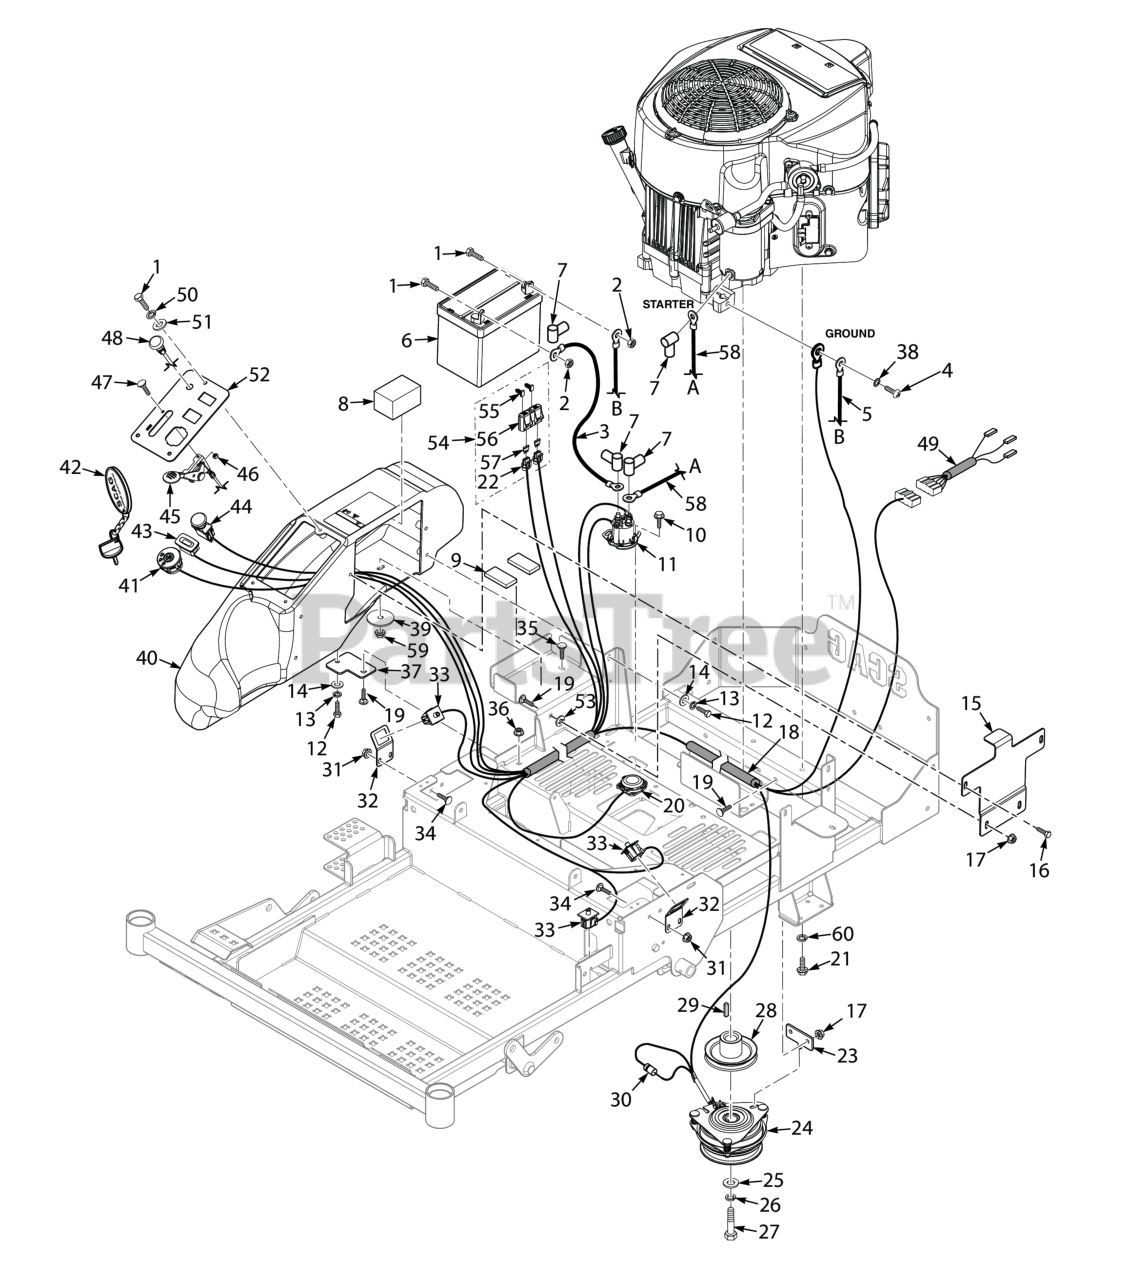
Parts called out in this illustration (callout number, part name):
1	Bolt, Hex Head 1/4-20 x .5" Battery, (Not Available Through Scag)
2	Nut, 1/4 - 20 Hex
3	Battery Cable, 18" Red w/Braid (25KA, 26DFI, 31DFI) - Kawasaki
4	Bolt, Hex Head M8 - 1.25 x 16 (48V / 52V)
5	Battery Cable, 31-1/2" Black (25KA, 26DFI, 31DFI) - Kawasaki
6	Battery, 12v - 230CCA
7	RUBBER BOOT
8	Pad, Battery - Rubber
9	Pad, Battery - Rubber
10	Screw, Self-Tapping 1/4-20 x 3/4
11	Solenoid, Sealed (Briggs & Stratton)
12	BOLT, SERRATED FLANGE HEX HEAD 5/16-18 X 3/4"
13	Lockwasher, 5/16 (.317 x .586 x .078) Helical Spring
14	Flatwasher, 5/16-.375 x .875 x .083 (35BV & 37BV-EFI)
15	Battery Hold Down
16	CAP SCREW, 5/16-18 X 1/2" SERRATED FLANGE HEX
17	Nut, Flange Head Elastic Stop 5/16-18
18	Wire Harness
19	Bolt, 5/16-18 x .75 RHSN Carriage
20	Switch, Double Pole - Twist
21	Bolt, Hex Head 3/8-16 x 1-1/4", Kawasaki FX / FT & FT-EFI
22	Fuse Holder Assembly
23	Plate, Anti-Rotation
24	Clutch, GT2 (SZL-61)
25	Flatwasher, 7/16-.469 x 1.75 x .25 (48, 52)
26	Lockwasher, 7/16� Spring
27	Bolt, Hex Head 7/16-20 x 3¼" w/Patch
28	Pulley, 4-1/2" - 1" Bore
29	Key, 1/4 x 1/4 x 1.25" Pulley Mtg.
30	Diode, 600V 6 Amp
31	Nut, Flanged Elastic Stop 1/4-20
32	Bracket, Switch
33	Switch, Double Pole - Plunger
34	Serr. Fl. Hex Head CPSCR, 1/4-20 x 3/4"
35	Bolt, Carriage 5/16-18x1" (large frame units only)
36	Nut, Serrated Flange 5/16-18 (Right Front Engine Mounting, Briggs and Kohler Only)
37	Mounting Bracket, Fuel Tanks Front
38	Lockwasher, 5/16" Ext. Tooth (Kohler x1)
39	Flatwasher, 3/8-.406 x 2.25" x .1875
40	Console Tank, SZL
41	Ignition Switch
42	Key, Assembly w/Fob
43	Hour Meter, Inductive
44	Switch, PTO - 10 Amp
45	Throttle Cable, Briggs & Stratton
46	Nut, Elastic Stop #10-24
47	Bolt, Carriage #10-24 x 1/2"
48	Choke Cable, Briggs & Stratton
50	Lockwasher, 1/4� Spring
51	Flatwasher, 1/4" (.312 x .750 x .065")
52	Instrument Panel w/Decal
53	Nut, Push-On 5/16-18
54	Double Fuse Assy.
55	Clip, Fuse Holder
56	Cover, Sealed Double
57	FUSE, 20 AMP BLADE TYPE AUTOMOTIVE
58	Battery Cable, 18" Red w/Braid (25KA, 26DFI, 31DFI) - Kawasaki
59	HEX NUT, ELASTIC STOP LOCK, 5/16-18
60	Lockwasher, 3/8" Spring, Kawasaki FX / FT & FT-EFI / B&S 32BV
